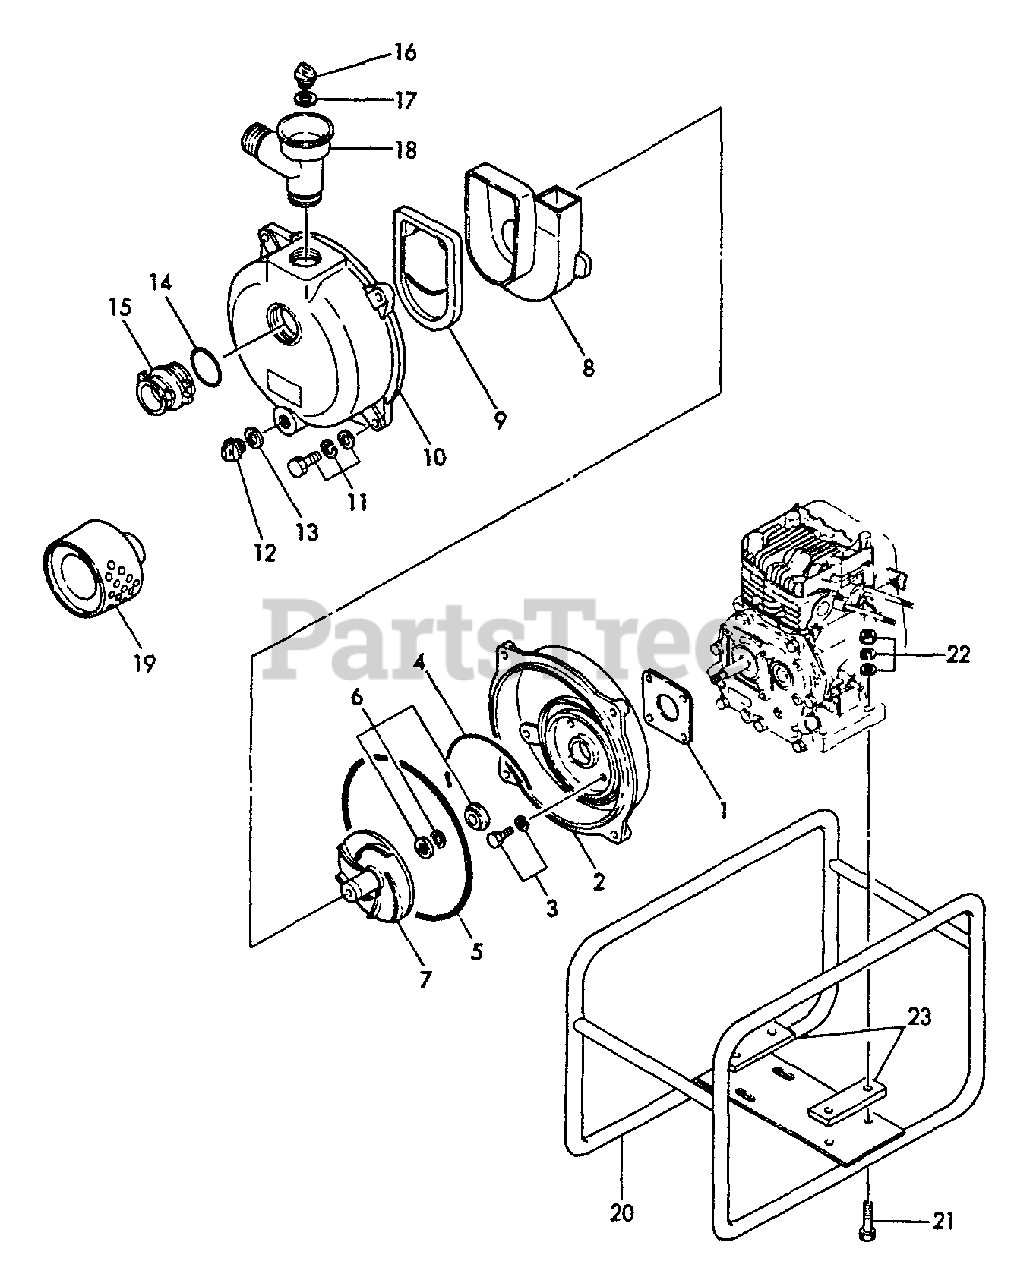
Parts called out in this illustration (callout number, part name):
1	GASKET, CASING
2	CASE, PUMP
3	BOLT, CASING
4	GASKET, CASING
5	O-RING, CASING
6	SEAL
7	IMPELLER
8	HOUSING
9	VALVE, STOP
10	COVER
11	BOLT, COVER
12	CAP, DRAIN
13	GASKET, CAP
14	O-RING, HOSE NIPPLE
15	HOSE NIPPLE
16	CAP, DELIVERY
17	GASKET, DELIVERY
18	BEND, DELIVERY
19	STRAINER, DEBRIS
20	BASE
21	BOLT, ENGINE
22	NUT, ENGINE
23	PLATE
